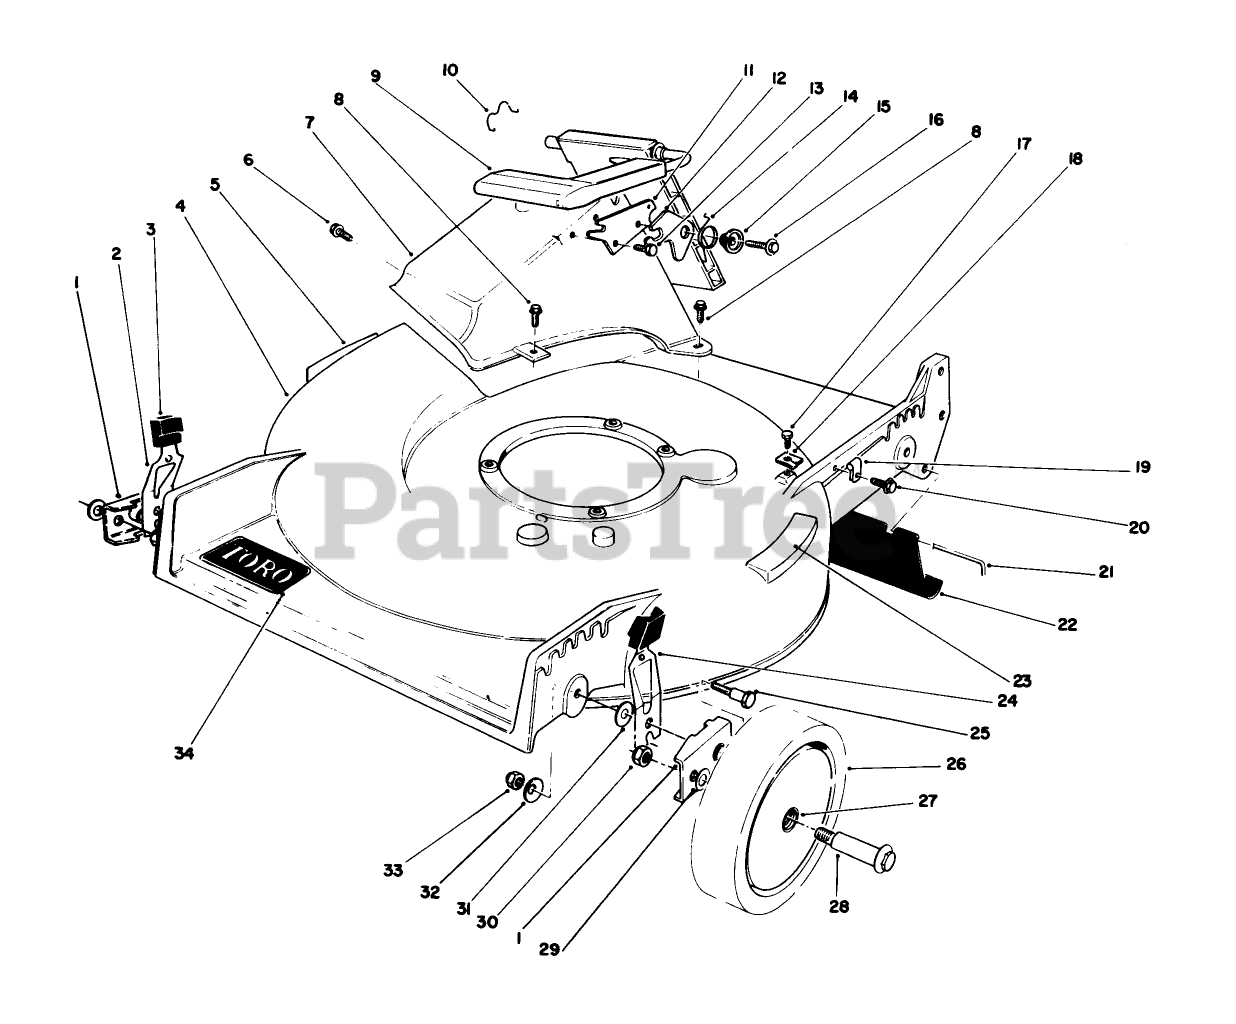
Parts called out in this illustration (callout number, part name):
1	HP PIVOT ARM ASM
3	KNOB-ARM
6	SCREW AND WASHER ASM
8	SCREW-HWH
10	DOOR RET SPRING
11	DOOR LATCH PLATE
12	SAFETY LATCH
13	SCREW-PLASTITE
14	TORSION SPRING
15	DOOR SPACER
16	SCREW-HWH
17	SCREW-HWHTF
18	CLAMP-CABLE
19	CLAMP-CABLE
20	SCREW
21	ROD-SHIELD
23	STEP PAD DECAL
25	PIVOT SCREW
27	BUSHING
28	WHEEL BOLT
29	WASHER
30	NUT-LOCK, NI
31	WASHER-PIVOT
32	WASHER-BELLEVILLE
33	NUT-LOCK, NI
34	DECAL
